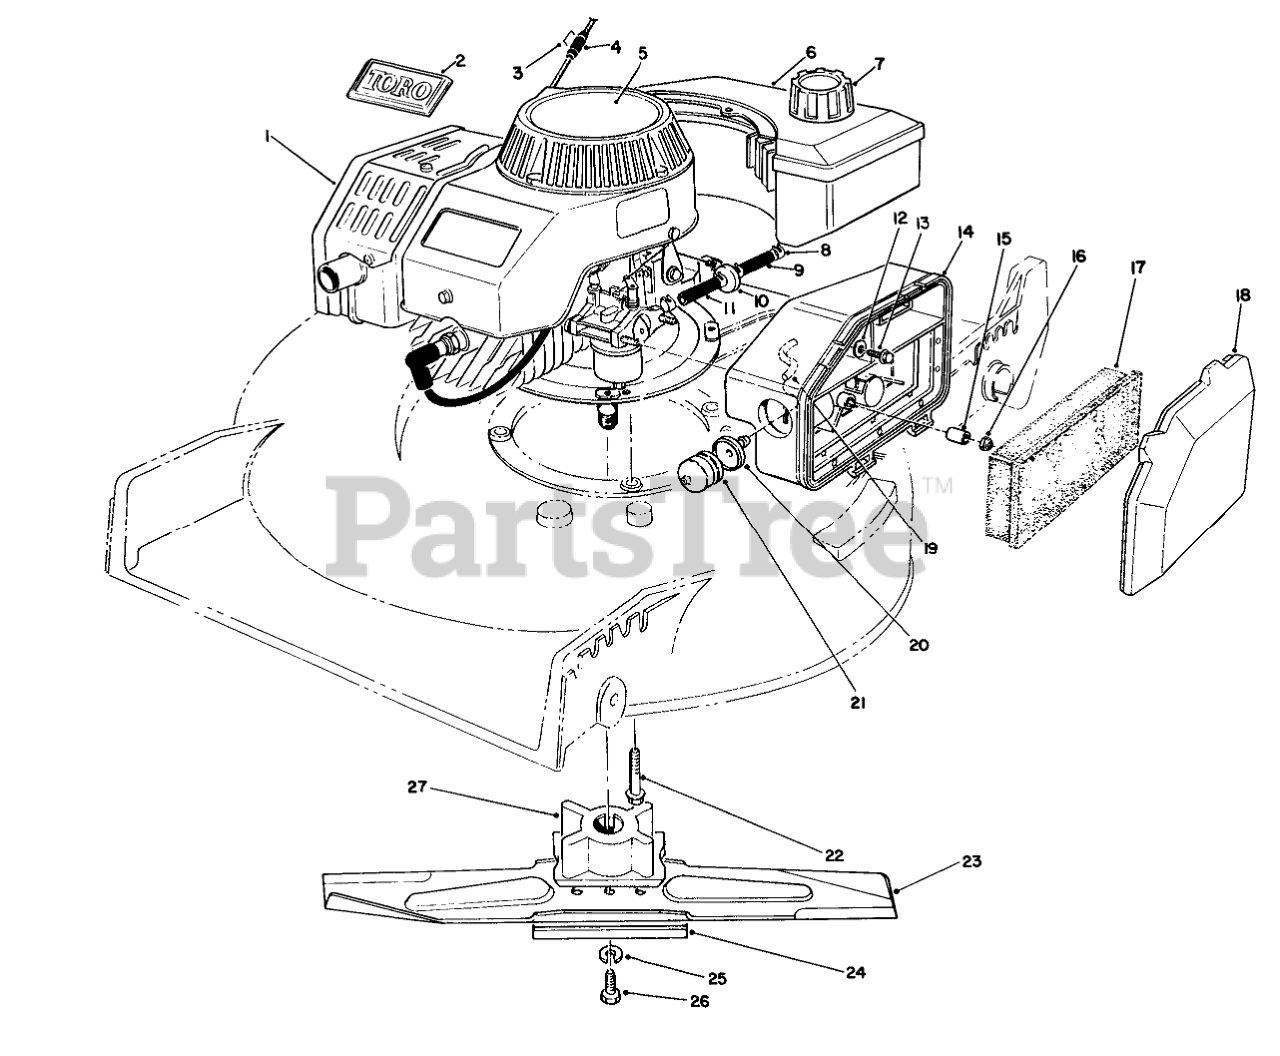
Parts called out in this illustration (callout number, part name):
1	Engine
2	TORO LOGO PLT
3	Staple
5	DECAL - 2 CYC RECOIL
6	Gas Tank Assembly
7	GAS CAP ASM
8	CLAMP-FUEL LINE
9	HOSE-FUEL
10	FILTER-FUEL
11	HOSE-FUEL
12	WASHER-FLAT
13	SCREW-HH
14	BODY-AIR CLEANER
15	SPACER
17	ELEMENT-AIR CLEANER
18	COVER-AIR CLEANER
19	HOSE-PRIMER
20	BODY-PRIMER
21	BULB-PRIMER
22	SCREW-HHF
23	Blade-21" (Incl. Ref. #24)
24	Stiffener
25	WASHER-LOCK
26	SCREW-BLADE
27	BLADE RETAINER
